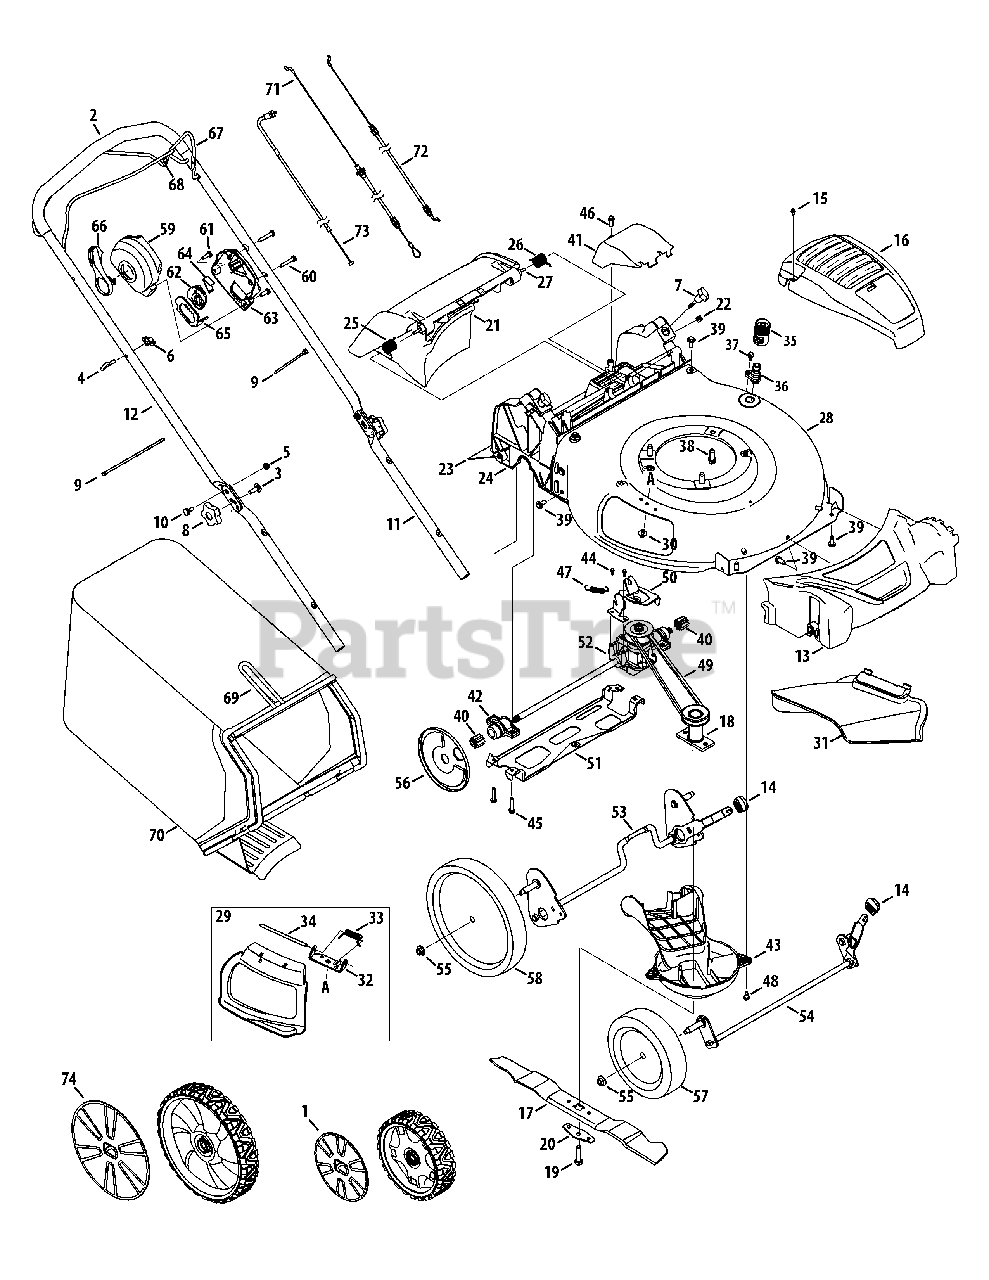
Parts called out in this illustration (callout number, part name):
1	Hubcap, 8"
3	Carriage Screw ,5/16-18
4	Rope Guide
5	Nut, Flange Lock, 1/4-20
7	Wing Nut
9	Cable Tie
10	Shdr. Screw, .375 x .126 x 1/4-20
11	Lower Handle
13	Front Cover
14	Adjustment Knob
15	Screw, HL, #12-16 x 1.00
16	Engine Shroud
17	Mulching Blade
18	Blade Adapter
19	Screw, 3/8-24 x 1.50
20	Blade Bell Support
21	Rear Discharge Door Assembly
22	Nut, Sq., 1/4-20
23	Trail Shield
24	Rear Baffle
25	Torsion Spring - RH
26	Torsion Spring - LH
29	Mulch Plug (Incl. 32-34)
31	Side Discharge Chute
32	Chute Deflector Bracket
33	Torsion Spring
35	Water Nozzle Adapter
36	Water Nozzle
37	Screw, Shldr., 1/4-20 x .50
38	Screw, tt, 3/8-16 x 1.00
39	Screw, 5/16-14 x .750
40	Spur Gear, 9T
41	Transmission Cover
42	Bearing Assembly
43	Engine Baffle
44	Screw, Hex Washer, .159 x .43
45	Screw, 1/4-15 x 1.25
46	Screw, 1/4-15 x .750
47	Exten. Spring, 2.675
48	Screw, Shldr., 1/4-20 x .50
50	Transmission Bracket
51	Rear Support Bracket
52	Transmission
53	Rear Axle Assembly
54	Front Axle Assembly
55	Flange Lock Nut, 3/8-16
56	Wheel Dust Cover
57	Front Wheel, 8 x2
58	Rear Wheel, 11 x 2
59	Control Housing Assembly
60	Screw, 1/4-15 x 1.50
61	Screw, 1/4-15 x .750
62	Speed Cable Actuater
63	Lower Control Housing
64	Shift Lever Spring
65	Cable Adjustment Plate
66	Speed Select Lever
67	Blade Control
68	Drive Control
69	Grass Catcher Frame
71	Speed Adjustment Cable
72	Control Cable
73	Speed Select Cable
74	Hubcap, 11"
